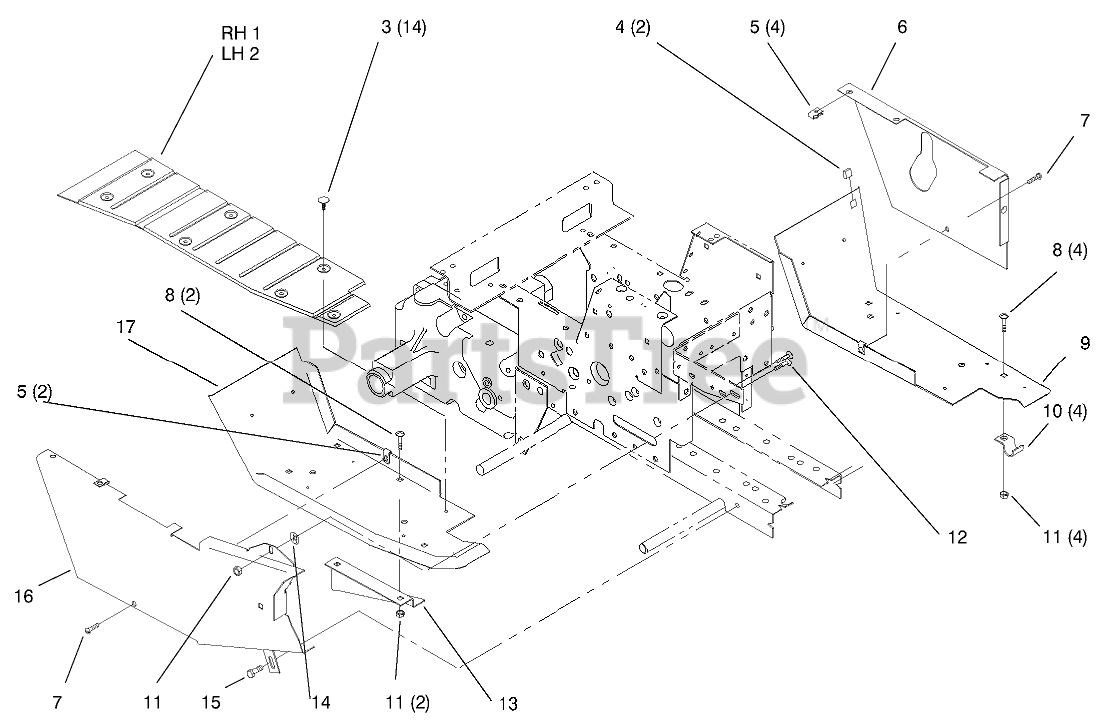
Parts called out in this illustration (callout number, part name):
1	PAD - FOOT
2	PAD-FOOT LH
3	FASTENER-PANEL
4	BUMPER
6	Cover-Side LH
7	SCREW-PPH
8	BOLT-CARR
9	Footrest LH
10	BRACKET
11	NUT-LOCK, NI
12	BOLT-CARR
14	NUT-PUSH
15	Bolt
16	Belt Guard
17	FOOTREST-RHR
